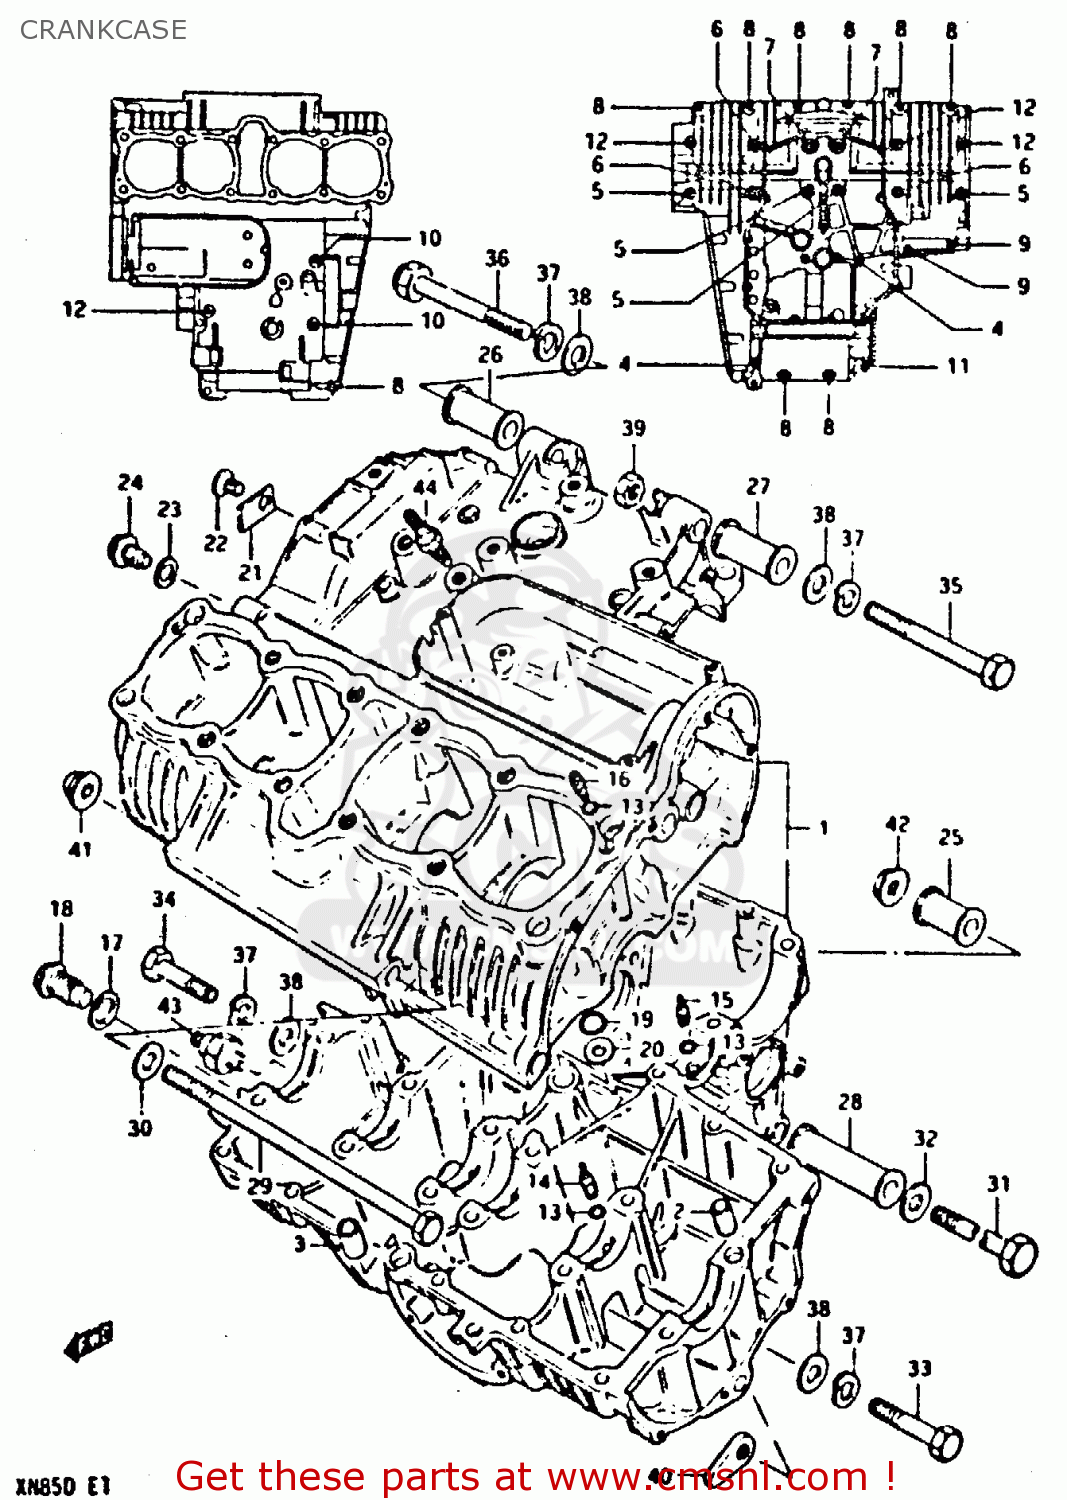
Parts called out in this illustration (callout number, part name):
1	CRANKCASE SET
2	PIN (11X20)(SUS)
3	PIN(10.4X13X22)
4	BOLT(6X105)
5	BOLT
6	BOLT
7	BOLT
8	BOLT
9	BOLT
10	BOLT
11	BOLT
12	BOLT (8X95)
13	O-RING,OIL GALLERY JET
14	JET
15	JET,OIL GALLERY
16	JET(12)
17	GASKET(16X22X2) (NAS)
18	PLUG
19	O RING(D:3.2,ID:12.9)
20	WASHER,THRUST
21	PLATE,OIL GALLERY PLUG
22	SCREW
23	GASKET(14X19.2X2) (NAS)
24	PLUG
25	SPACER
26	SPACER,ENGINE MOUNT
27	SPACER,ENGINE MOUNT
28	SPACER
29	BOLT
30	WASHER
31	BOLT
32	WASHER
33	BOLT
34	BOLT 10X40
35	BOLT (10*95)
36	BOLT
37	LOCK WASHER
38	WASHER
39	NUT (10MM)
40	NUT
41	NUT
42	NUT
43	SWITCH ASSEMBLY
44	GAUGE ASSEMBLY,OIL TEMPERATURE
